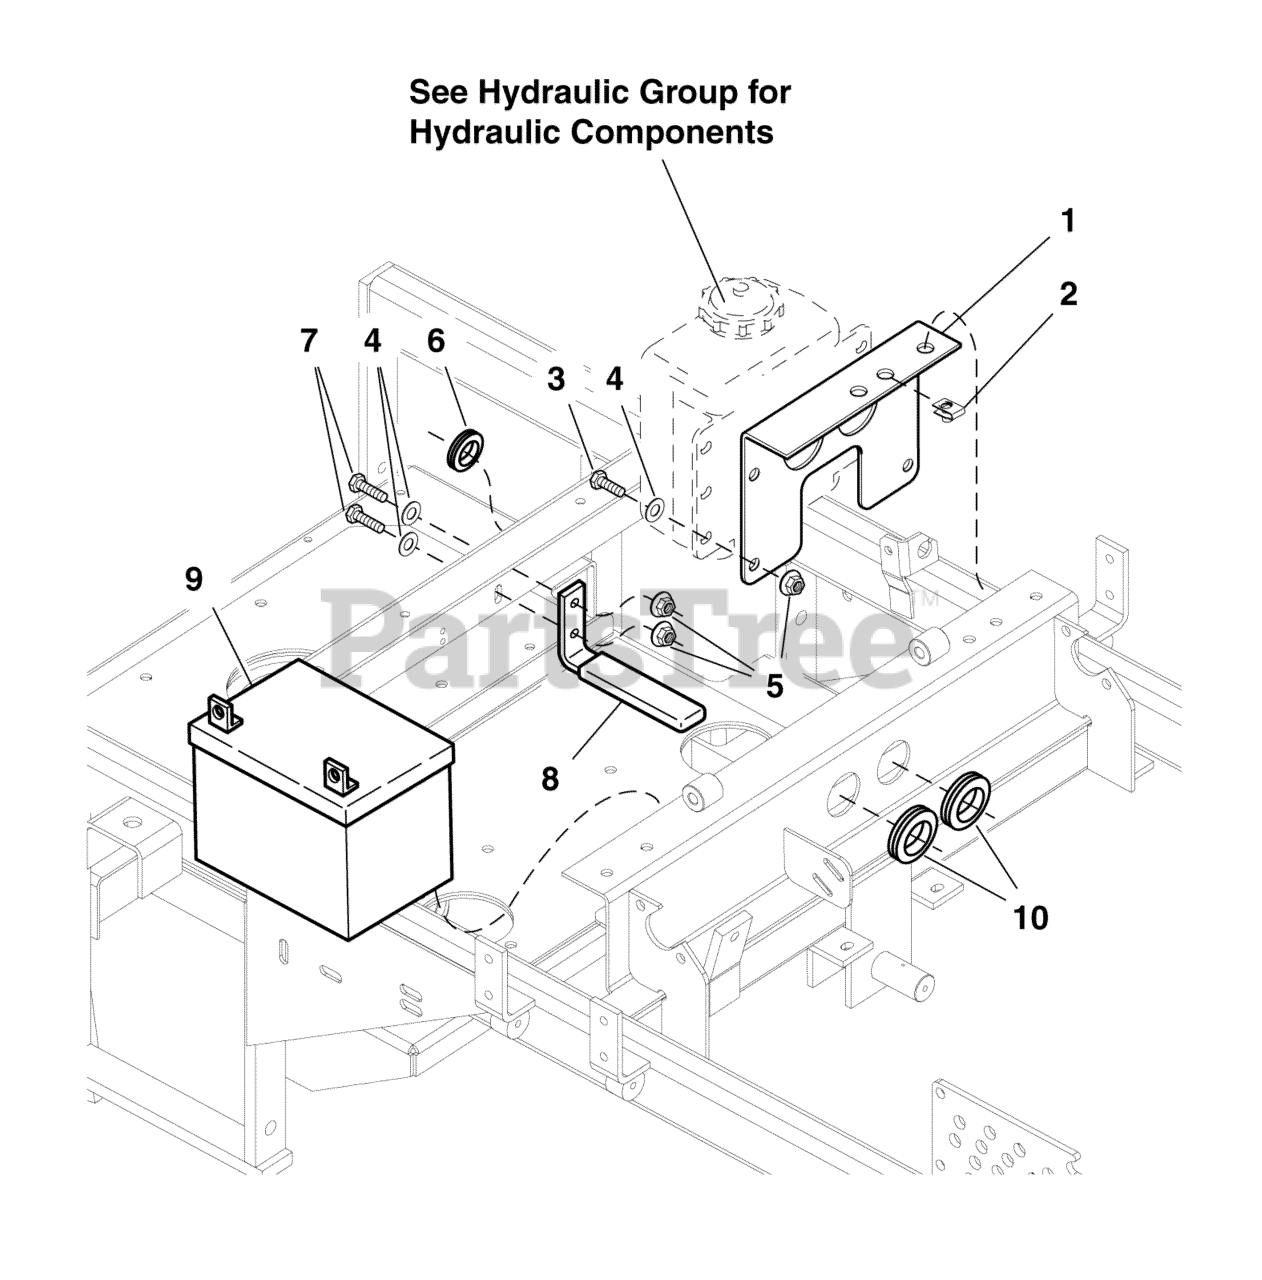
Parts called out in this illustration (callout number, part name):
1	MOUNT, Reservoir
2	BODY CLIP, 3/8-16
3	BOLT, 5/16-18 X 3/4 GD5
4	WASHER, 5/16" SAE
5	NUT, 5/16-18 HEX SERRATED FLANGE (SMALL)
6	GROMMET, 7/8"
7	BOLT, 5/16-18 X 1 GD5 YZ
8	ASSM, BATTERY RETAINER
9	BATTERY, Lawn & Garden, 12V (BCIU1, 340 CCA)
10	GROMMET, 1-1/4"
